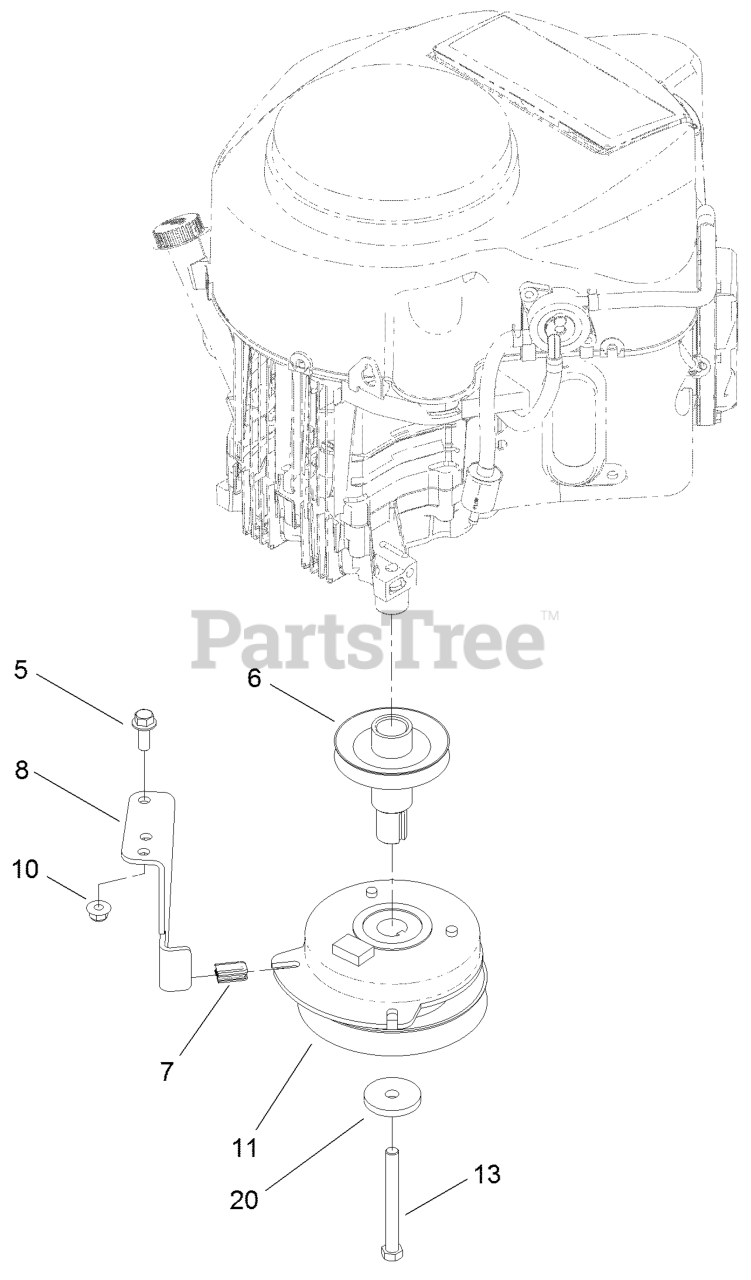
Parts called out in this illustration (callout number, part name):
5	SCREW-HHF 3/8-16 X 1
6	PULLEY-ENGINE
7	ISOLATOR-CLUTCH
8	STOP-CLUTCH
10	NUT-HF, NI
11	CLUTCH-PTO
13	SCREW-HH
20	WASHER-CLUTCH
